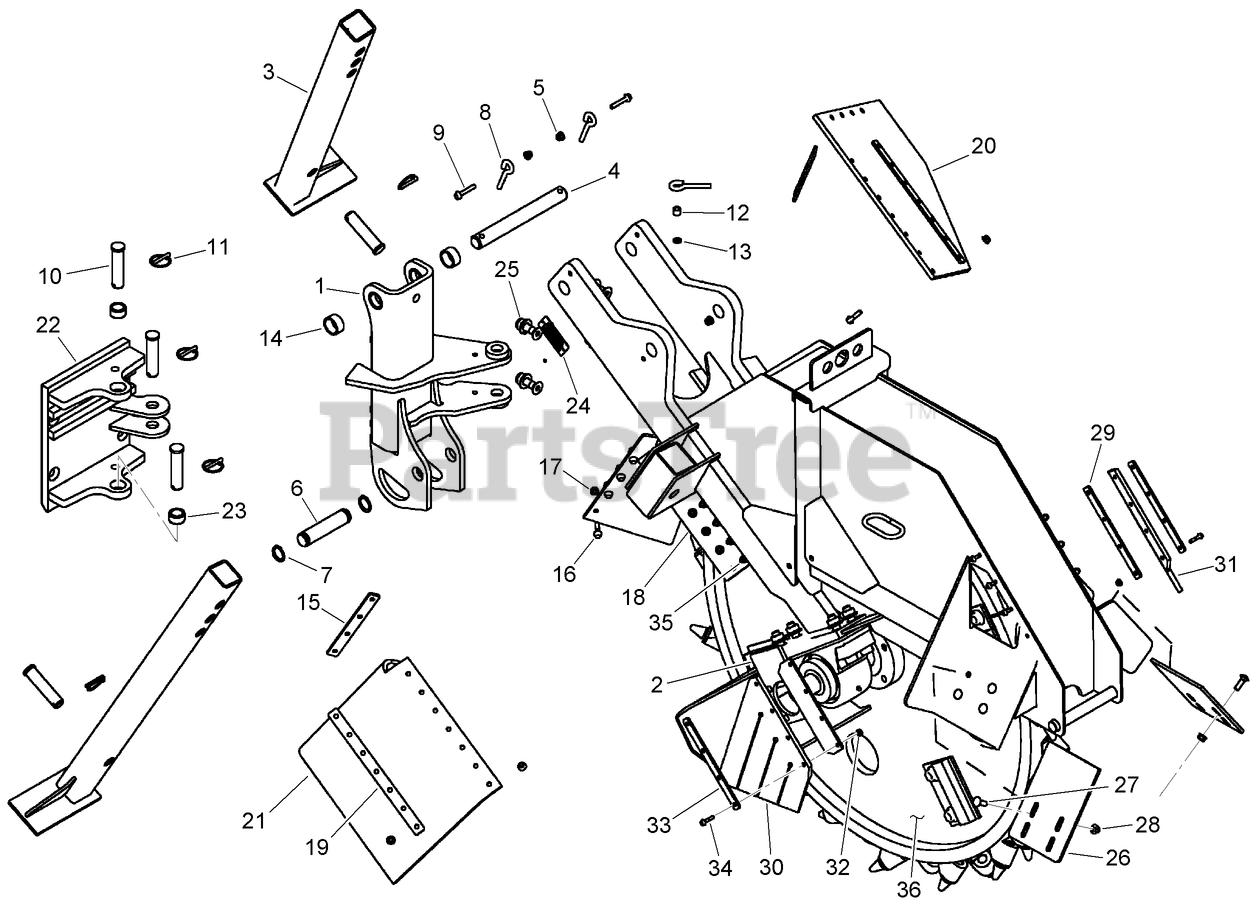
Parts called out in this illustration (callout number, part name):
1	PIVOT - Plow
2	PLATE - Motor Cover
3	LEG - Support Stand
4	PIN - Cylinder
5	NUT-TORQUE, PREVAILING
6	PIN-CLEVIS
7	RING-RETAINING
8	PIN-RETAINER
9	SCREW, METRIC FLANGE w/BODY - M8 x 50
10	PIN-PIVOT
11	PIN-KLIK
12	SPACER-13 mm (1/2 inch) long
13	WASHER-FLAT
14	SPACER - Pin
15	PLATE - Front Skirt
16	SCREW, METRIC FLANGE FULL - M8 x 25
17	NUT, METRIC HEX FLANGE - M8, Zinc
18	BRACKET - Side Skirt
19	PLATE - Skirt Side
20	SKIRT - Front, LH
21	SKIRT - Front, LH
22	SLIDE-QUICK ATTACH
23	BUSHING-UPPER
24	PLATE - Serial Number
25	TACK-FASTENER, STEEL
26	PLATE - Discharge Slide
27	BOLT - Round Hd .375 x 1.25 GR5 ZND
28	NUT-Serr Flg 3/8-16 UNC GR5 ZND
29	PLATE - Discharge Angle
30	FLAP - Side Discharge
31	FLAP - Side Discharge
32	NUT, METRIC HEX FLANGE - M6, Zinc
33	PLATE - Discharge Skirt
34	SCREW, METRIC FLANGE w/BODY - M6 x 30
35	SCREW-HH
36	ASSEMBLY - Rocksaw Axle
